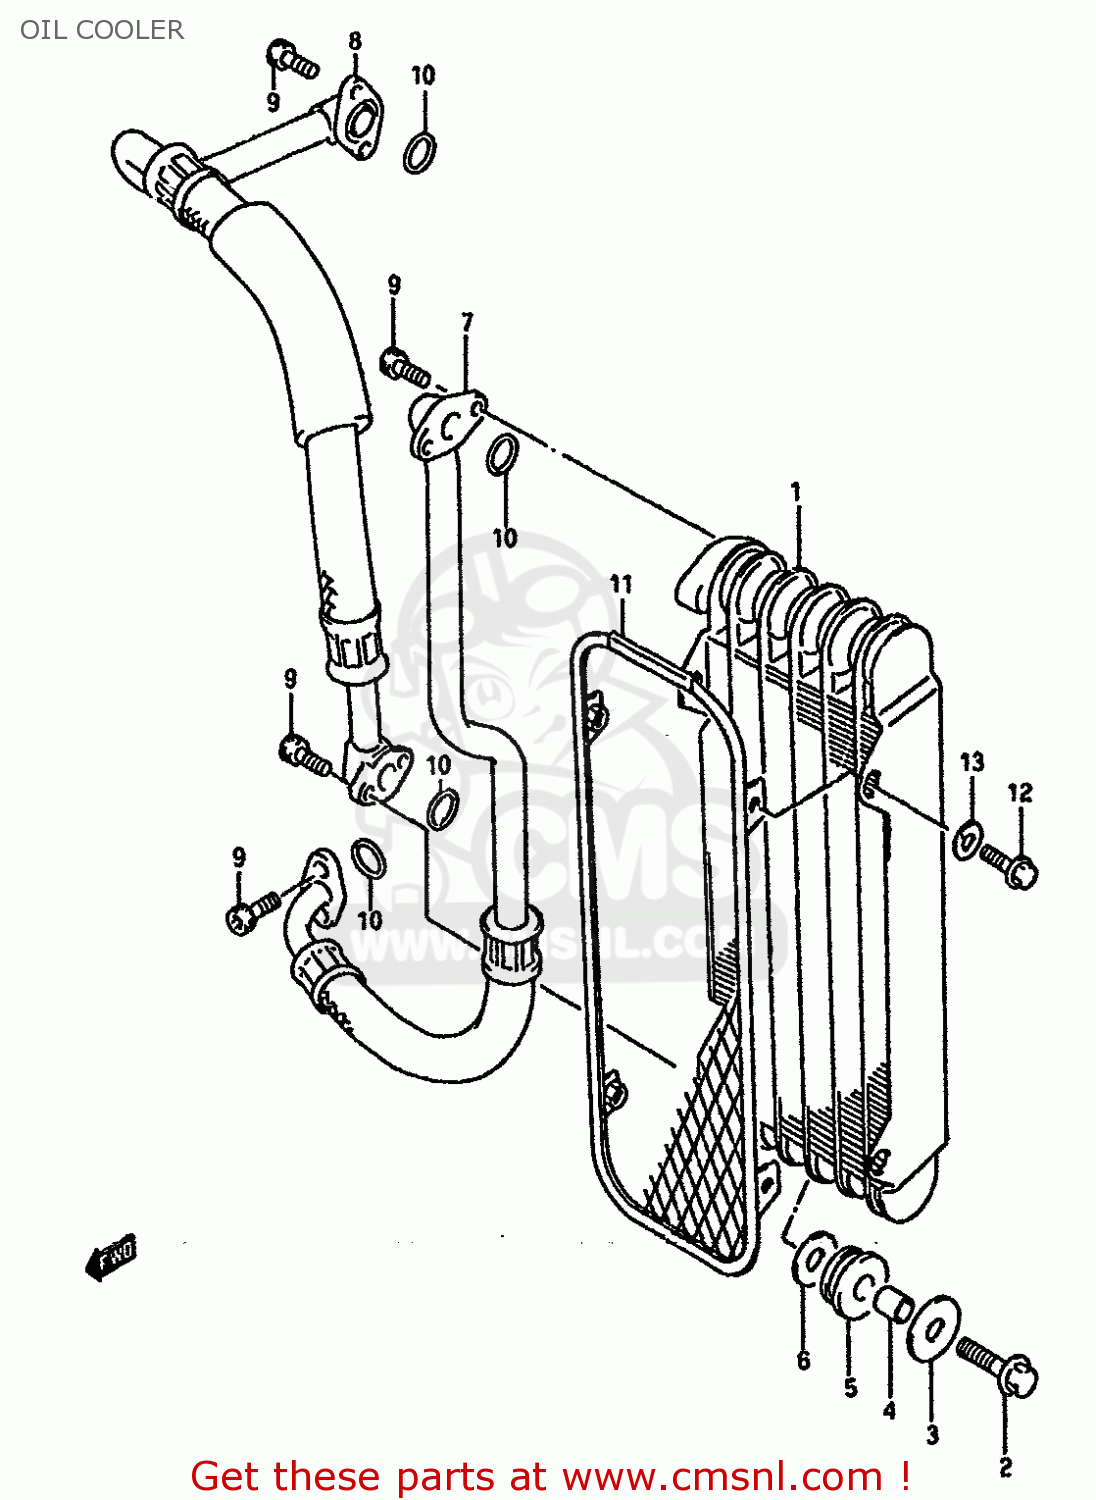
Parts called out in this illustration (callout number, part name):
1	COOLER ASSY,OIL
2	BOLT
3	WASHER (8.5X20X1.6)
4	SPACER (8.8X12X11.6)
5	CUSHION,OIL COOLER
6	WASHER(8.5X23X1.2)
7	HOSE,OIL COOLER NO.1
8	HOSE,OIL COOLER NO.2
9	BOLT
10	O RING(D:2.4,ID:12.3)
11	BUMPER,OIL COOLER
12	BOLT
13	WASHER,LOCK
